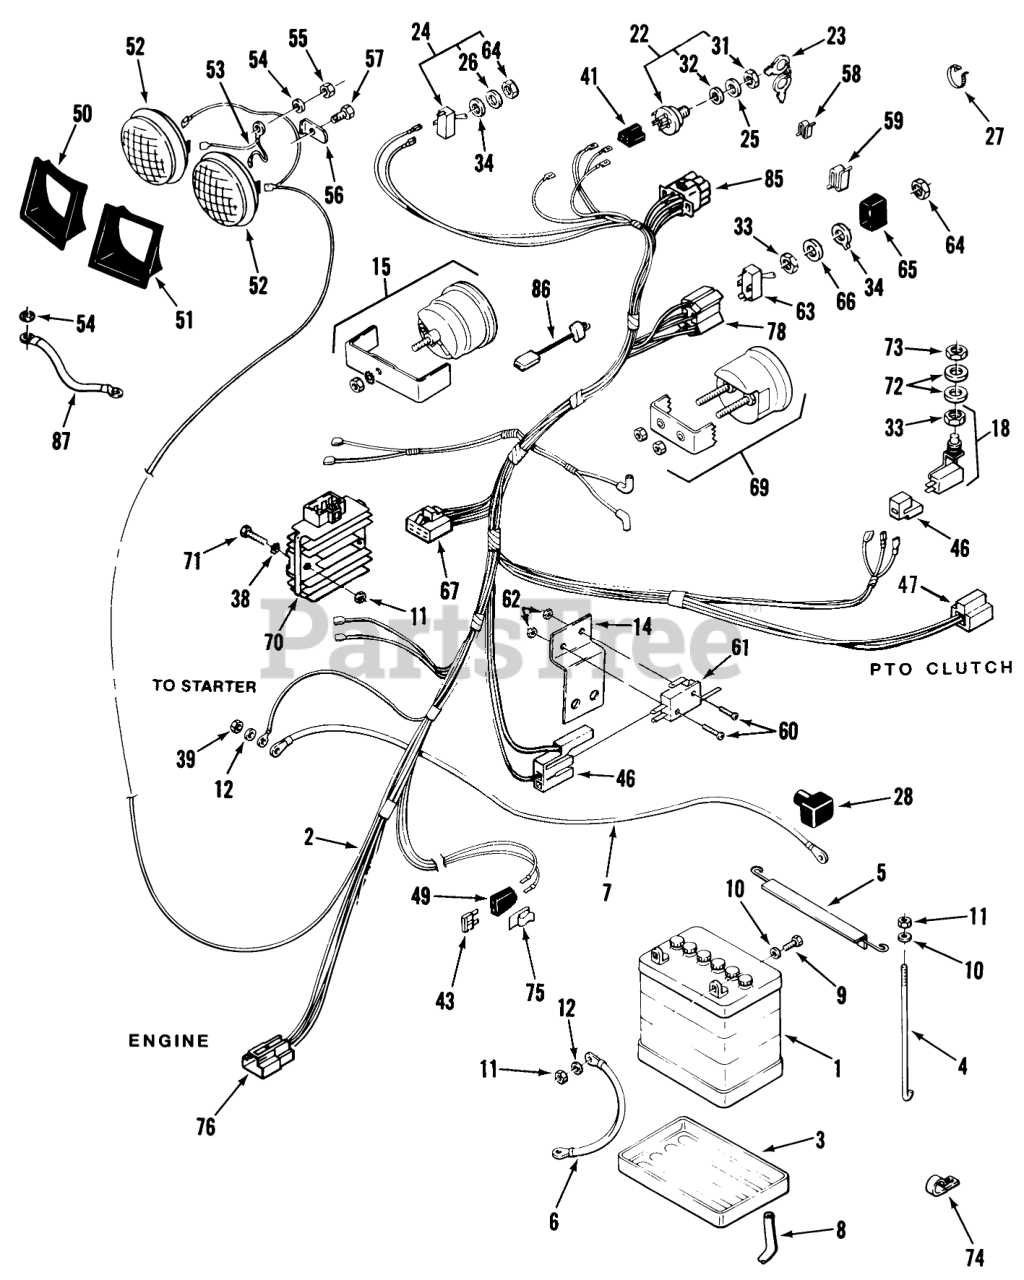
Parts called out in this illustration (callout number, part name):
1	Battery
2	Wiring Harness 252-H
2	MAIN-HARN & WIR DIA
3	TRAY-BATTERY
5	HOLDDOWN-BATTERY
6	WIRE - 14" BLACK
7	ASSY WIRE
8	TUBE-21" BATTERY DRAIN
9	Bolt
11	Nut
12	Washer
14	BRKT SWITCH BRAKE R
15	Hourmeter 257-H Only (Includes 108768 clamp, 915538 #10-24 Nut & 920120 Ext. Tooth Lockwasher)
18	Seat Switch
22	Ignition Switch (includes items 31 & 32)
23	Ignition Key
23	KEY PADDED
24	Light Switch (includes items 33 & 34)
25	Washer
26	Washer
27	PLASTIC TIE
28	Boot
32	LOCKWASHER
33	NUT-HEX, SPECIAL
34	TAB-WASHER
38	LOCKWASHER
39	Nut
41	CONNECTOR-5 WAY-SERV
43	FUSE-BLADE, 15 AMP
43	FUSE-BLADE, 25 AMP
46	CONNECTOR BODY
47	CONNECTOR BODY
49	FUSE-BLOCK ASS'Y
50	BEZEL-HEADLIGHT, RH
51	BEZEL-HEADLIGHT, LH
52	HEADLAMP
53	LIGHT GROUND WIRE
54	Washer-Lock
55	Nut
56	LOCK-HEADLIGHT
57	Bolt
58	CLIP
59	SPEED CLIP
59	CLIP-CABLE
60	Screw
61	SWITCH
62	NUT HEX 4-40 ELAST
63	Electric Clutch Switch (includes items 33, 34 & 64)
65	COVER-PTO SWITCH
66	WASHER
67	6 Terminal Connector 112-C Only
69	Voltmeter (Includes 109650 Clamp & 5924 #10-32 Nut)
70	Voltage Regulator 252-H (Kawasaki #21066-2004)
70	Voltage Regulator 257-H (Kawasaki #21066-2056)
71	HHCS 1/4-20X1" WHIZ
72	Washer
73	NUT-HEX SPECIAL
74	CLAMP
75	MOUNTING-CLIP CONN
76	3-CONTACT LOCK-TYPE
78	CONNECTOR 5 WAY
85	9-Terminal Connector
86	LIGHT-OIL INDICATOR
87	WIRE-LIGHT GROUND
